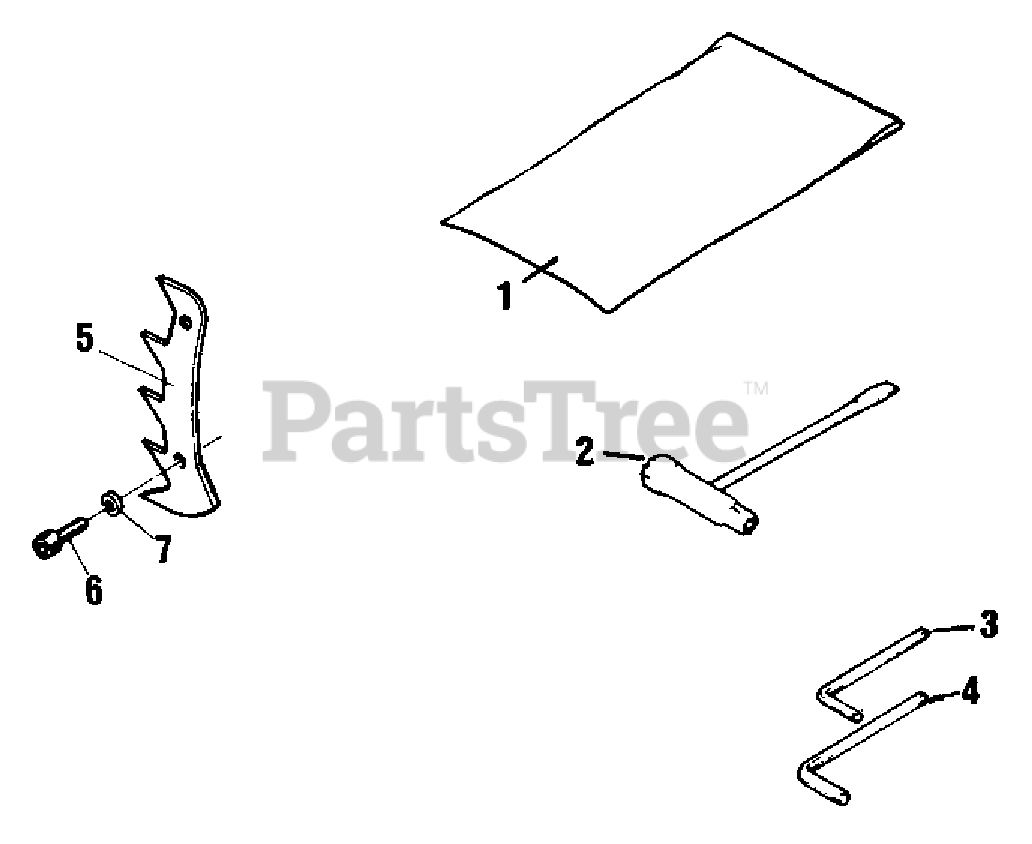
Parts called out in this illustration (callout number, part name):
1	BAG, TOOL
2	T-WRENCH
3	HEX KEY - 3mm
4	HEX KEY - 4mm
6	SCREW - 5X12
7	LOCKWASHER - 5
